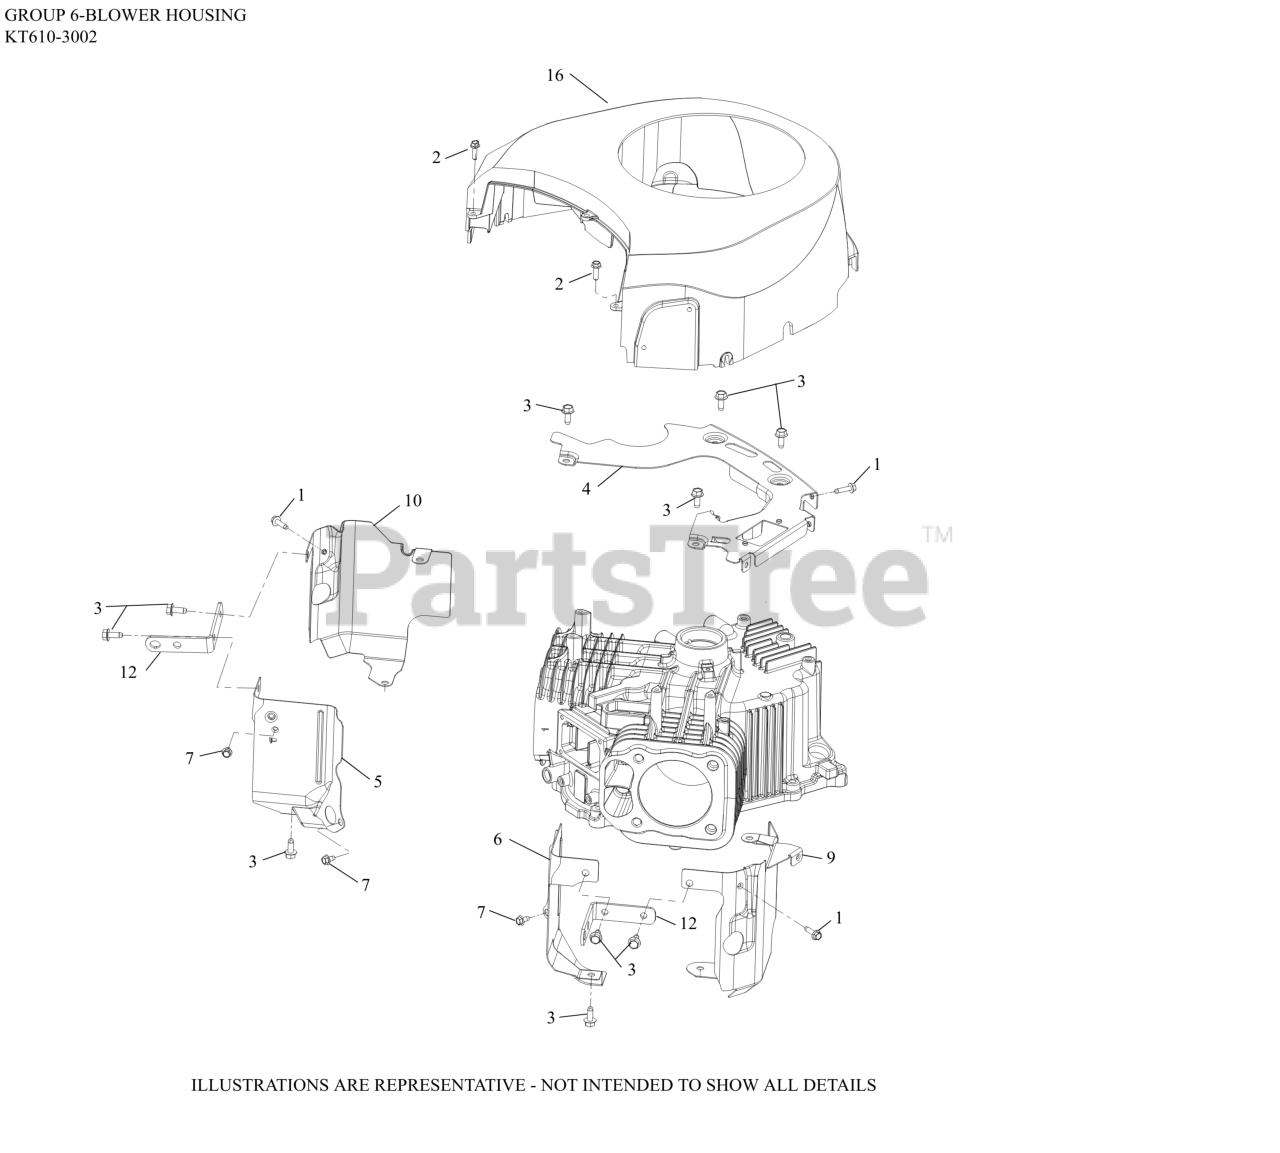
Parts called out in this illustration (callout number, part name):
1	SCREW, THD FRM-USE 25 086 473-S
2	SCREW, HI-LOW
3	SCREW, THREAD FORMING
4	PLATE, BACKING
5	BAFFLE, VALLEY #1
6	BAFFLE, VALLEY #2
7	SCREW, THREAD FORMING
9	BAFFLE, LEFT BARREL
10	BAFFLE, RIGHT BARREL
12	STRAP, LIFTING
16	KIT, BLOWER HOUSING
